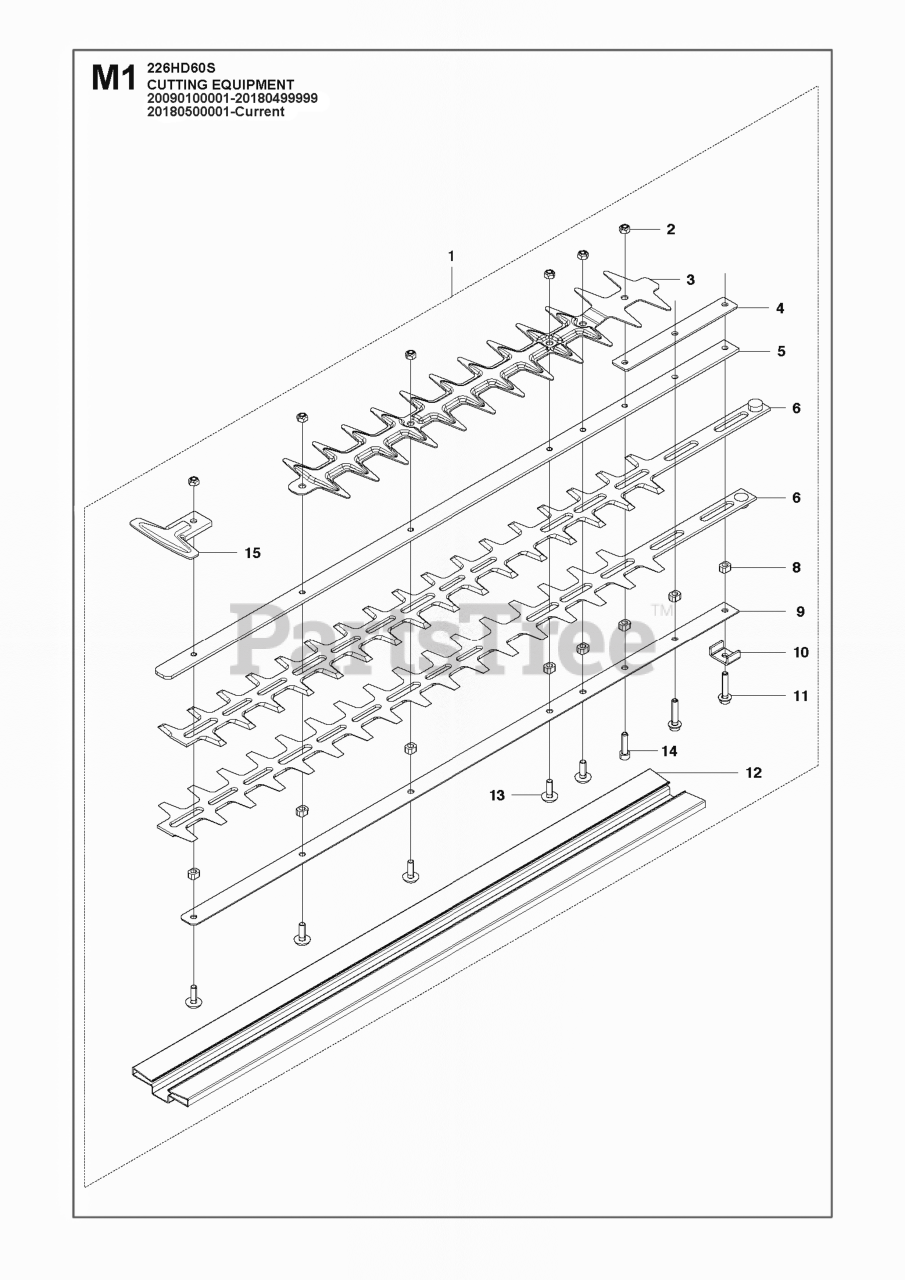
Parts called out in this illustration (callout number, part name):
1	BLADE KIT
1	BLADE ASSY 226HD60S
3	BLADE GUARD
5	PLATE.UPPER T454411110
6	RP BLADE
6	BLADE 226HD60S
9	PLATE, LOWER
11	BOLT
12	BLADE COVER
13	BOLT
13	SCREW
14	BOLT
15	COVER TOP PROTECTION
